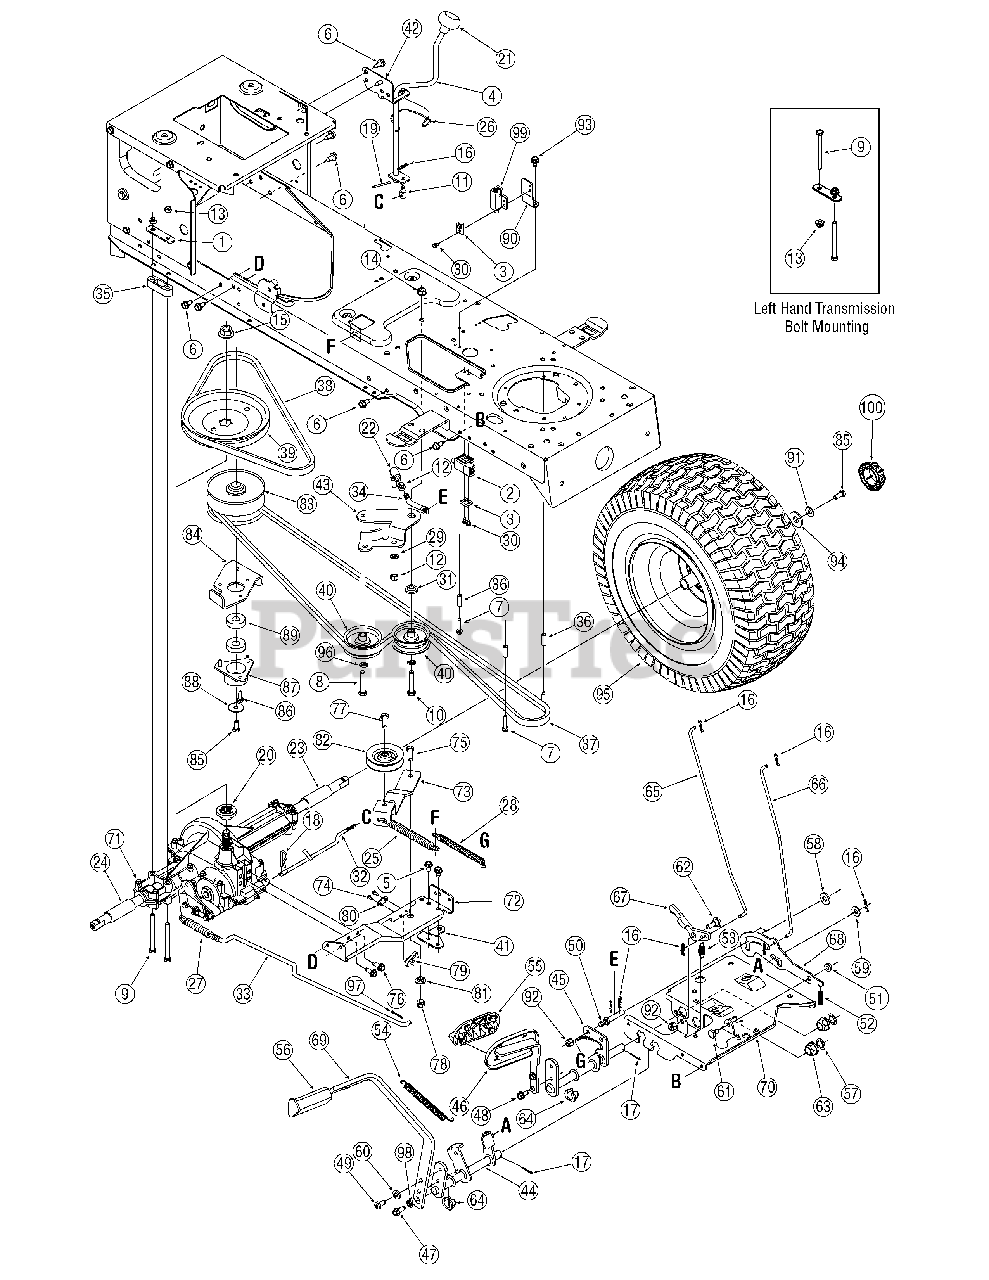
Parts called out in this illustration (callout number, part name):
2	Switch, Interlock
3	Plate, Switch
4	Lever Assembly, Shift
5	Screw, 5/16-18, 0.500
6	Screw, 5/16-12, 0.750
7	Screw, 1/4-20, 1.250
8	Screw, Sems, 3/8-16, 1.500
9	Screw, 5/16-18, 3.50, Gr5
10	Screw, 3/8-16, 2.00, Gr5
11	Adjustment Ferrule 1/4-20 x 1.
12	Nut, Hex, 3/8-24, Gr5
13	Nut, Flange Lock, 5/16-18, GrF
14	Nut, Flange Lock, 3/8-16, GrF
15	Nut, Flange, 9/16-18, Gr2
16	Pin, Cotter,.072 Dia. x 1.13
17	Pin, Cotter, 3/32, 1.0
18	Cotter Pin, Internal,.125 Dia.
19	Pin, Cotter, 1/8 x 1.25
20	Pulley Hub, 5/8 Spline
22	Ball Joint
23	Sleeve,.758 x.821 x 3.3125
24	Sleeve,.758 x.821 x 2.4375
25	Spring, Extension,.62 Dia x 6.12
26	Spring Clip, Shifter
27	Spring, Extension,.59 OD x 4.00
28	Spring, Extension,.50 Dia x 6.37
29	Washer, Lock, 3/8
30	Screw, #10-16,.50
31	Spacer, Shoulder, 1.00 x.38 x.38
32	Rod, Shift
34	Idler Rod, Adjustable, 3/8
35	Spacer,.68
36	Spacer,.260 x.372 x 1.030
37	Belt, V-Type
38	Belt, V-Type
39	Pulley, V-Type, 7.25 Dia.
40	Idler Pulley, Flat 2.75 OD
41	Bracket, Shift
42	Bracket, Shift, F-N-R
47	Screw, 5/16-18, 0.875
48	Screw,5/16-18, 0.750
49	Screw, 5/16-18, 0.750
50	Pin, 3/8-16 x 2.68
51	Nut, Flange Lock, 5/16-18, Gr5
52	Spring, Compression.,.405 x 1.17
53	Spring, Extension,.50 OD x 1.41
54	Spring, Extension,.50 OD x 6.37
56	Pad, Brake
57	Washer, Flat,.64 x 1.24 x.06, HT
58	Washer, Flat,.385 x.870 x.092
59	Washer, Flat,.406 x.875 x.059
60	Washer, Flat,.344 x.750 x.120
61	Screw, Shoulder.437 Dia x.162
62	Screw, Shoulder,.50 x.27 Lg
63	Bearing, Hex Flange
64	Split Bearing, Hex Flange
65	Rod, Brake Lock
66	Rod, Cruise Control
67	Latch, Cruise Control
68	Bracket, Lockout
71	Transmission, Single Speed
72	Bracket Assembly, Torque
73	Bracket, Idler
74	Screw, #8-18 x.50
75	Screw, 3/8-16, 1.00
76	Screw, 5/16-18,.625
77	Screw, 3/8-16, 1.250
78	Nut, Lock, 3/8-16, Nylon
79	Switch Spring, Short
80	Plate, Insulator
81	Spacer, Shoulder
82	Pulley, V-Type, 3.06
83	Pulley Ass’y, Variable Speed
84	Bracket, Pulley
85	Screw, 5/16-24,.750
86	Screw, 1/4-20,.625
88	Washer, Flat
89	Ball Bearing
92	Nut, Flange Lock, 3/8-16, GrF
93	Screw, 1/4-20 x.500
94	Flat Washer,.350 x 1.59 x.062
95	Rim Only w/ Valve Stem
96	Flat Washer, .407 x .812 x .135
97	Pin, Cotter, 3/32 x .750
98	Lock Washer, 5/16
99	Switch
100	Hub Cap
